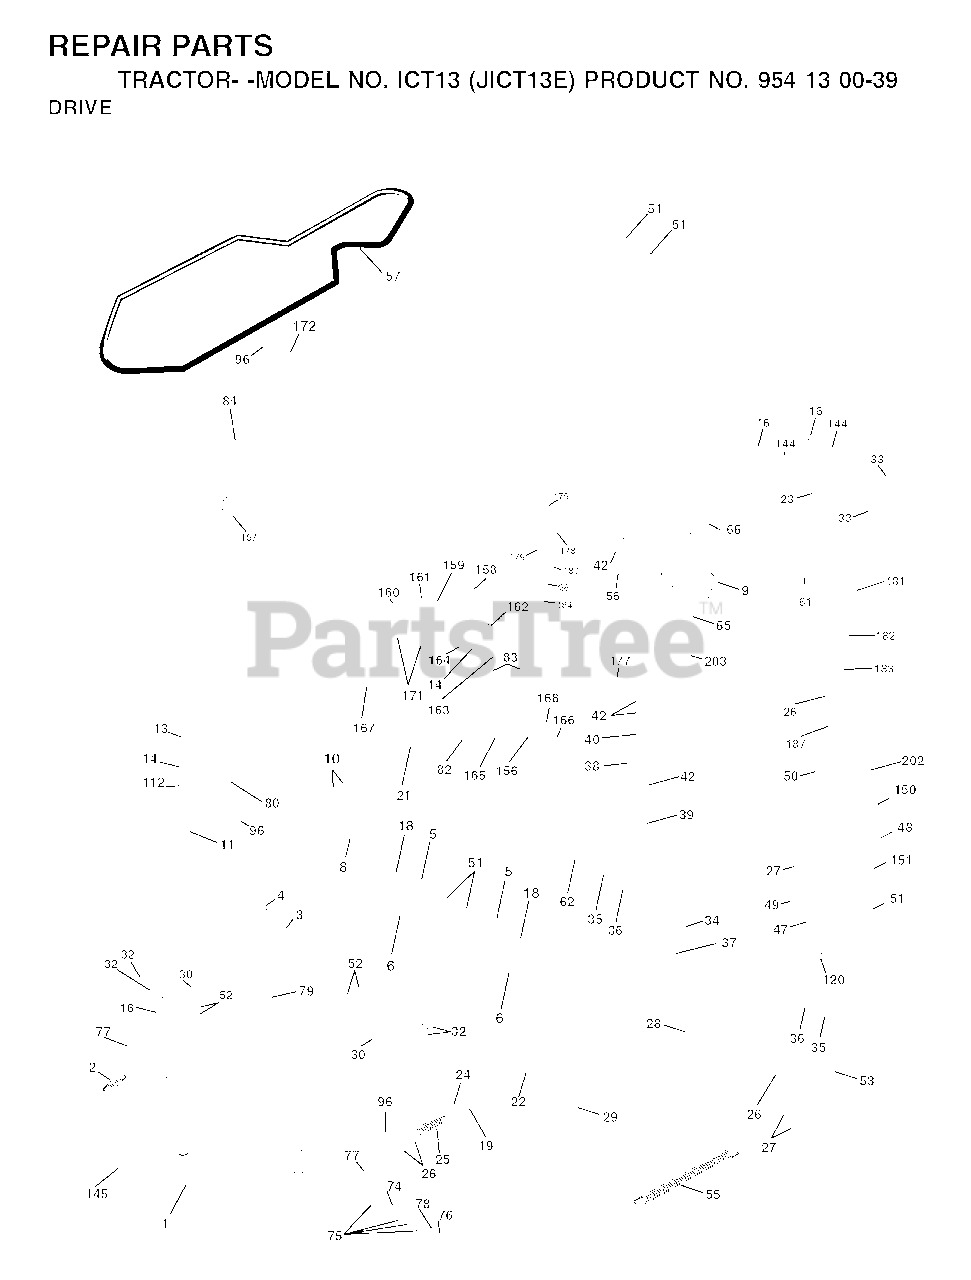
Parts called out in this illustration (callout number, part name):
2	SPRING,BRAKE RETURN
4	RETAINING RING LT
5	STRAP TORQUE
6	SCREW 5/16"
8	ROD SHIFT
9	CLUTCH ASSY
10	PIN COTTER
11	WASH-SHFT PLT LT
13	BOLT 1/4-28X3/4
14	LOCKWASHER
16	NUT.71038.31-18.HEX.NYLOCK
19	NUT
21	KNOB T (1/2-HOLE)
24	NUT
25	SPRING ROD LT
27	COTTER PIN
28	ROD BRAKE PARK LT
29	PLUNGER CAP
30	BRKT, MOUNT TRNSAXLE
32	BOLT
33	BOLT
35	BEARING.NYLON
36	WASHER LT
37	DRIVE PIN
38	PULLEY.FLAT
42	WASHER
47	IDLER PULLEY
48	BELLCRANK, CLUTCH
49	RETAIN BELT
50	BOLT
51	LOCKNUT
52	LOCKNUT
53	LINK, CLUTCH LT
55	SPRING, RETURN LT
57	V-BELT.KEV.111"
61	SCREW 3/8-16X3/4
62	PEDAL COVER T
65	LOCKWASHER
66	KEEPER BELT ENGINE
74	SPACER AXLE
76	E-RING LT
77	SQUARE KEY
80	ARM SHIFT
82	SPRING,TORSION
83	WASHER
96	RETAINER M
112	WASHER LT
120	NUT LOCK FLG 3/8-16 UNC
144	WASHER
150	BUSHING.BELLCRANK.GRD.DR
151	WASHER 12/32X2X10GA
156	WASHER.SRRTD.5/16
158	BRACKET
159	HUB
161	BOLT
162	NUT.CROWNLOCK.1/4
165	RP BRACKET
167	BRACKET
168	BOLT.SHOULDER.5/16-18X
180	PULLEY.FLAT.IDLER
182	KEEPER BELT
183	PULLEY.V-IDLER
184	SCREW.HXWSH.3/8
187	SCREW
197	NYLINER SNAP 5/8" ID
202	BOLT.3/8-16X1.50
